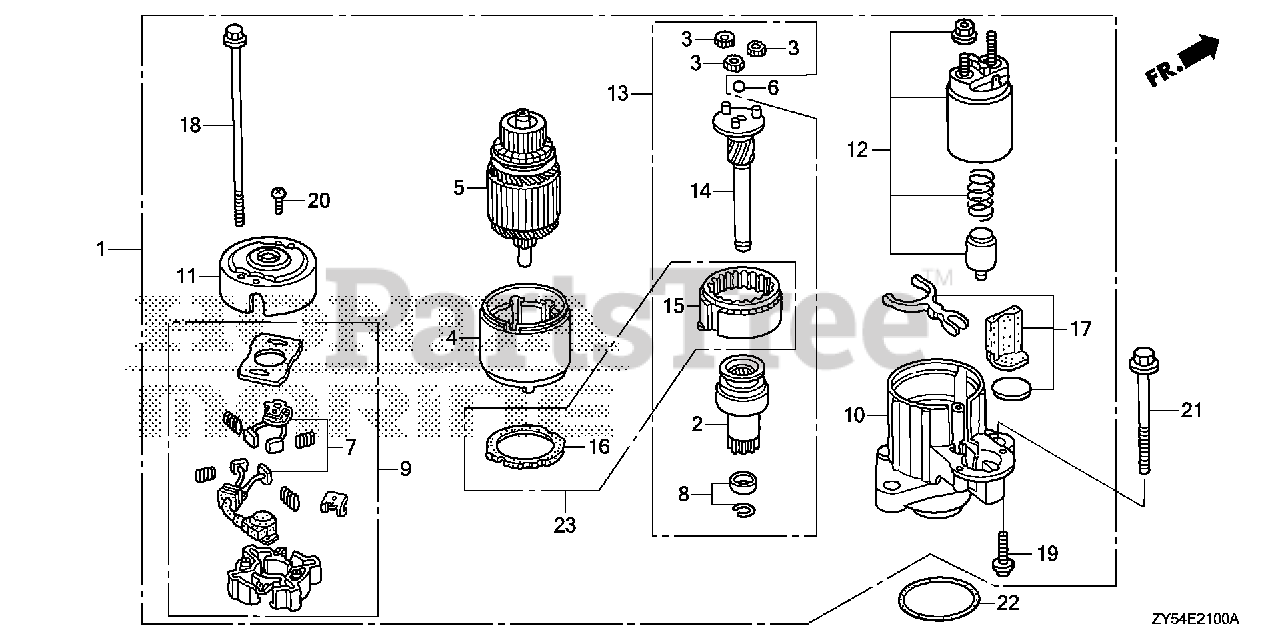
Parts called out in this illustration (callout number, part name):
1	STARTER MOTOR ASSY.
2	CLUTCH, OVERRUNNING
3	GEAR ASSY., PLANETARY
6	BALL, STEEL
7	BRUSH SET
8	STOPPER SET, SLEEVE
9	HOLDER, BRUSH
10	BRACKET, FR.
11	BRACKET, RR.
12	SWITCH ASSY., MAGNET
13	SHAFT ASSY., CLUTCH
14	SHAFT ASSY., GEAR
15	GEAR ASSY. (INNER)
16	GASKET
18	BOLT A, THROUGH
19	SCREW, PAN (6X22)
19	SCREW, PAN (6X22) (SPECIAL)
20	SCREW, PAN (5X8)
21	BOLT, FLANGE (10X90)
22	O-RING (59.4X3.1)
23	GEAR ASSY. (INNER)
